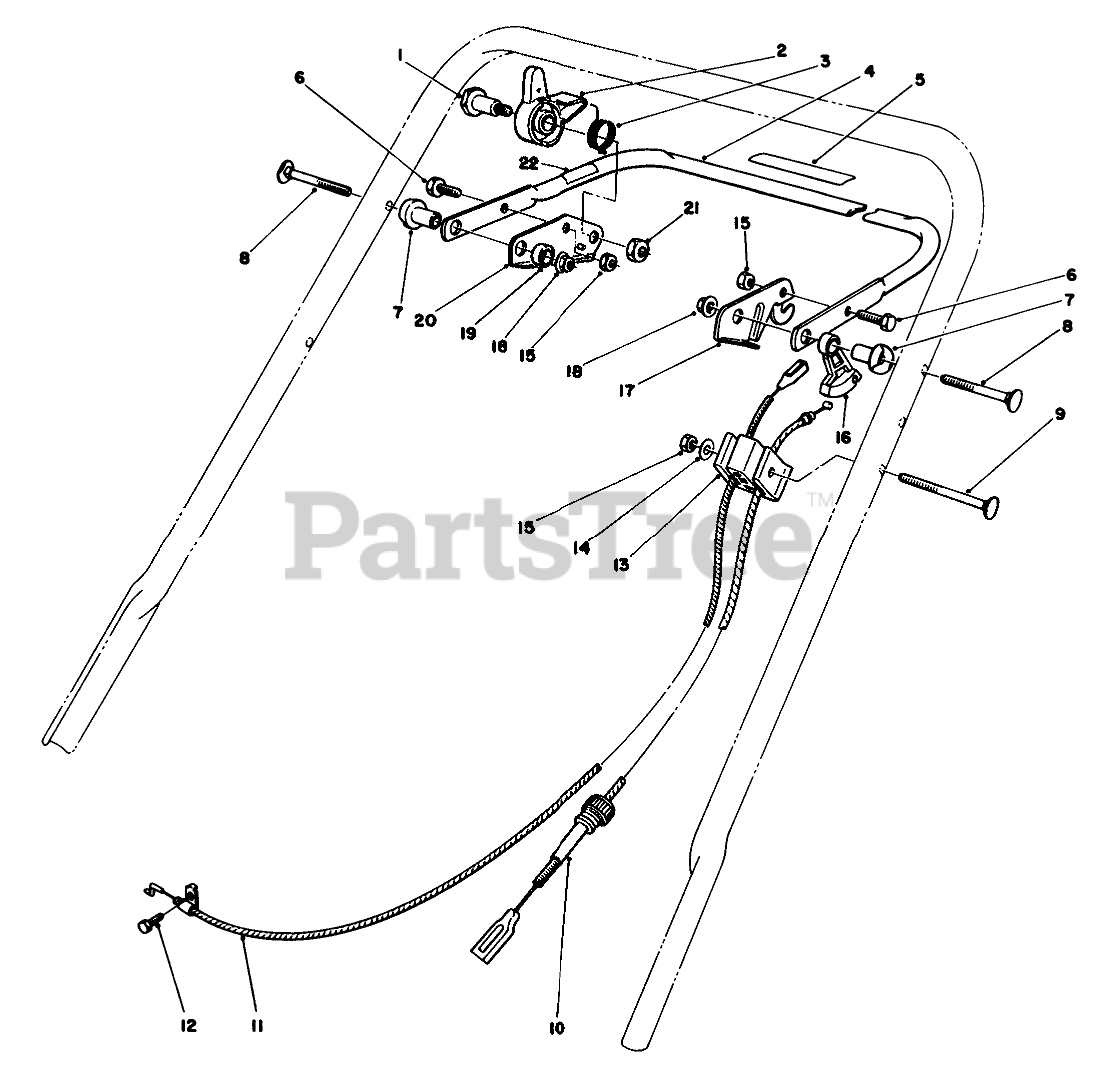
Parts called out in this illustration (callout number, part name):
1	SHOULDER BOLT
2	NEUTRAL LOCKOUT
3	Belt-Drive
4	Bar-Control
5	Decal-Variable Speed
6	SCREW-HH
7	SPACER-SUPPORT
8	5/16-18 X 2 HNDLE SCREW
9	HANDLE SCREW
10	CABLE-TRACTION
11	BRAKE CABLE
12	SCREW-HH
13	SUPPORT-CABLE
14	WASHER-FLAT
15	NUT-LOCK, NI
16	LEVER-TRACTION
17	Lever-Control
18	NUT-LOCK, NI
19	SPACER-NYLON
20	Bracket-Lockout
21	NUT-LOCK, NI
22	Decal-Locknut(used on units with serial no. 6000101-6001100)
